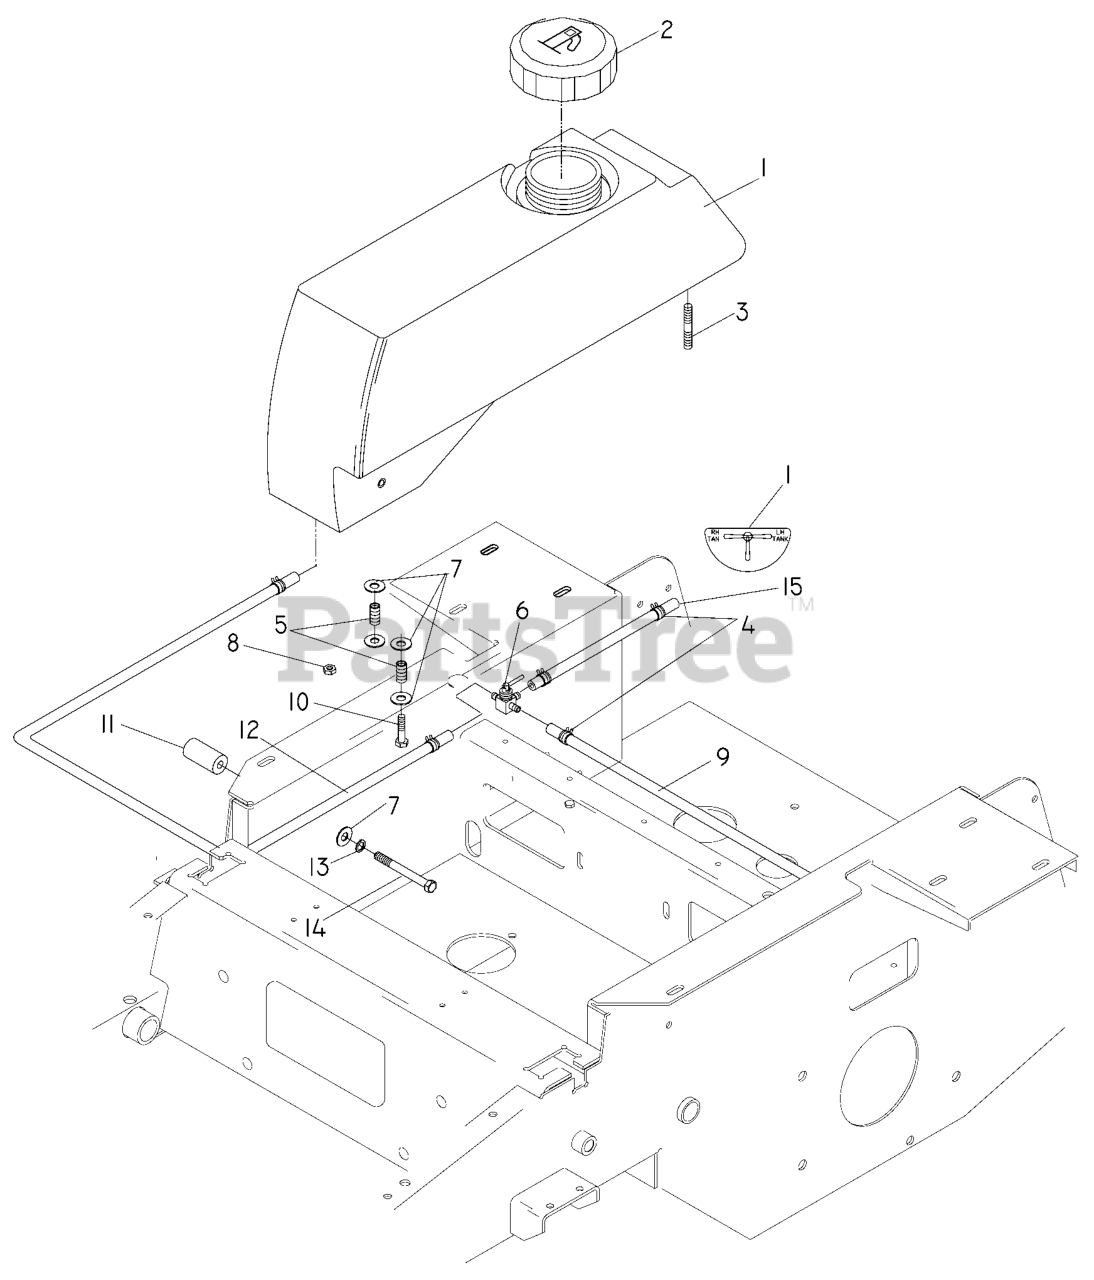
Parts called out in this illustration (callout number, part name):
1	FUEL TANK RT
2	FUEL CAP ANTI-SPLASH
3	STUD, 5/16C
4	HOSE CLAMP
6	FUEL VALVE
7	WASHER 5/16 FLAT
8	NUT 5/16C CENTERLOCK
10	HCS 5/16C X 1
11	TANK SPACER
13	WASHER.LOCK.HVY.HLCL.SPR.5/16
14	HCS 5/16C X 4
15	FUEL LINE 13"
16	DECAL, FUEL VALVE
